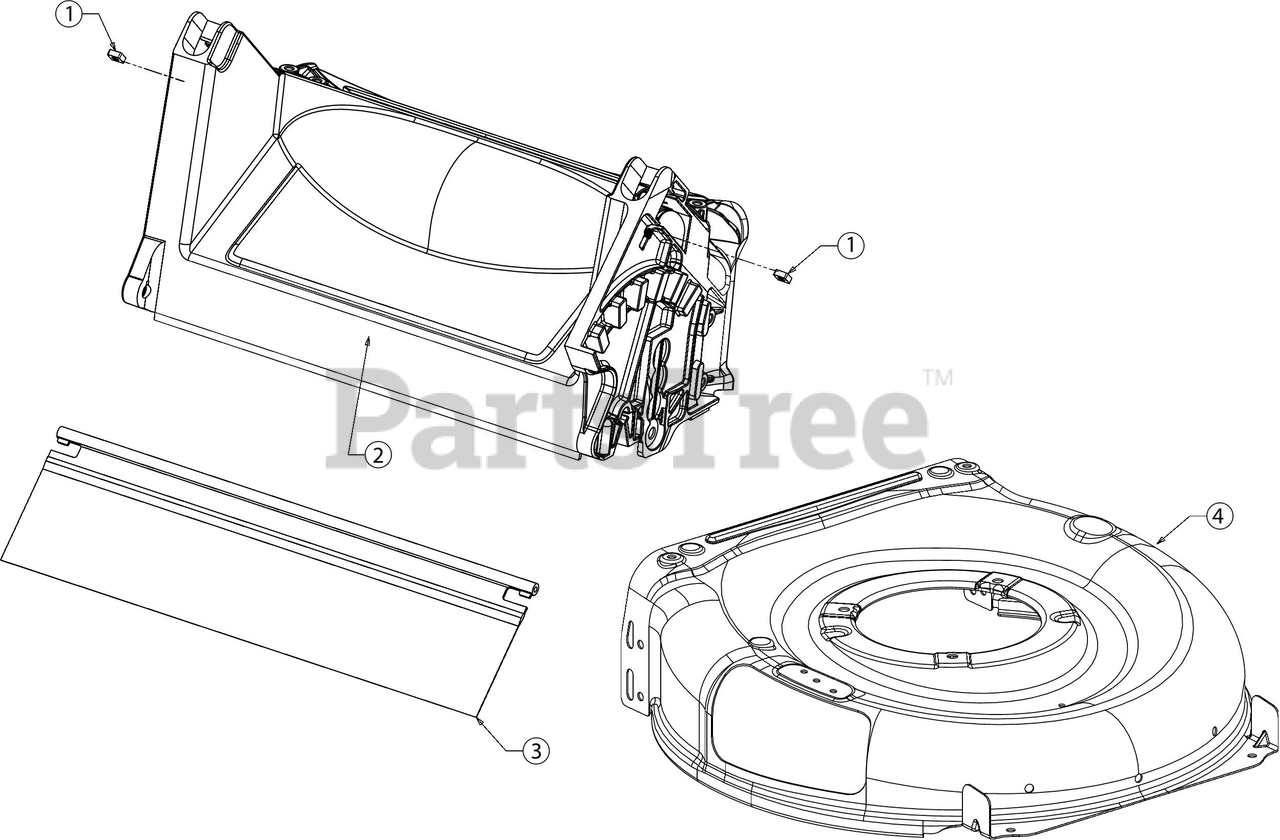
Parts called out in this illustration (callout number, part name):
1	SQUARE NUT 1/4-20
2	REAR BAFFLE ASSEMBLY
3	TRAILSHIELD
